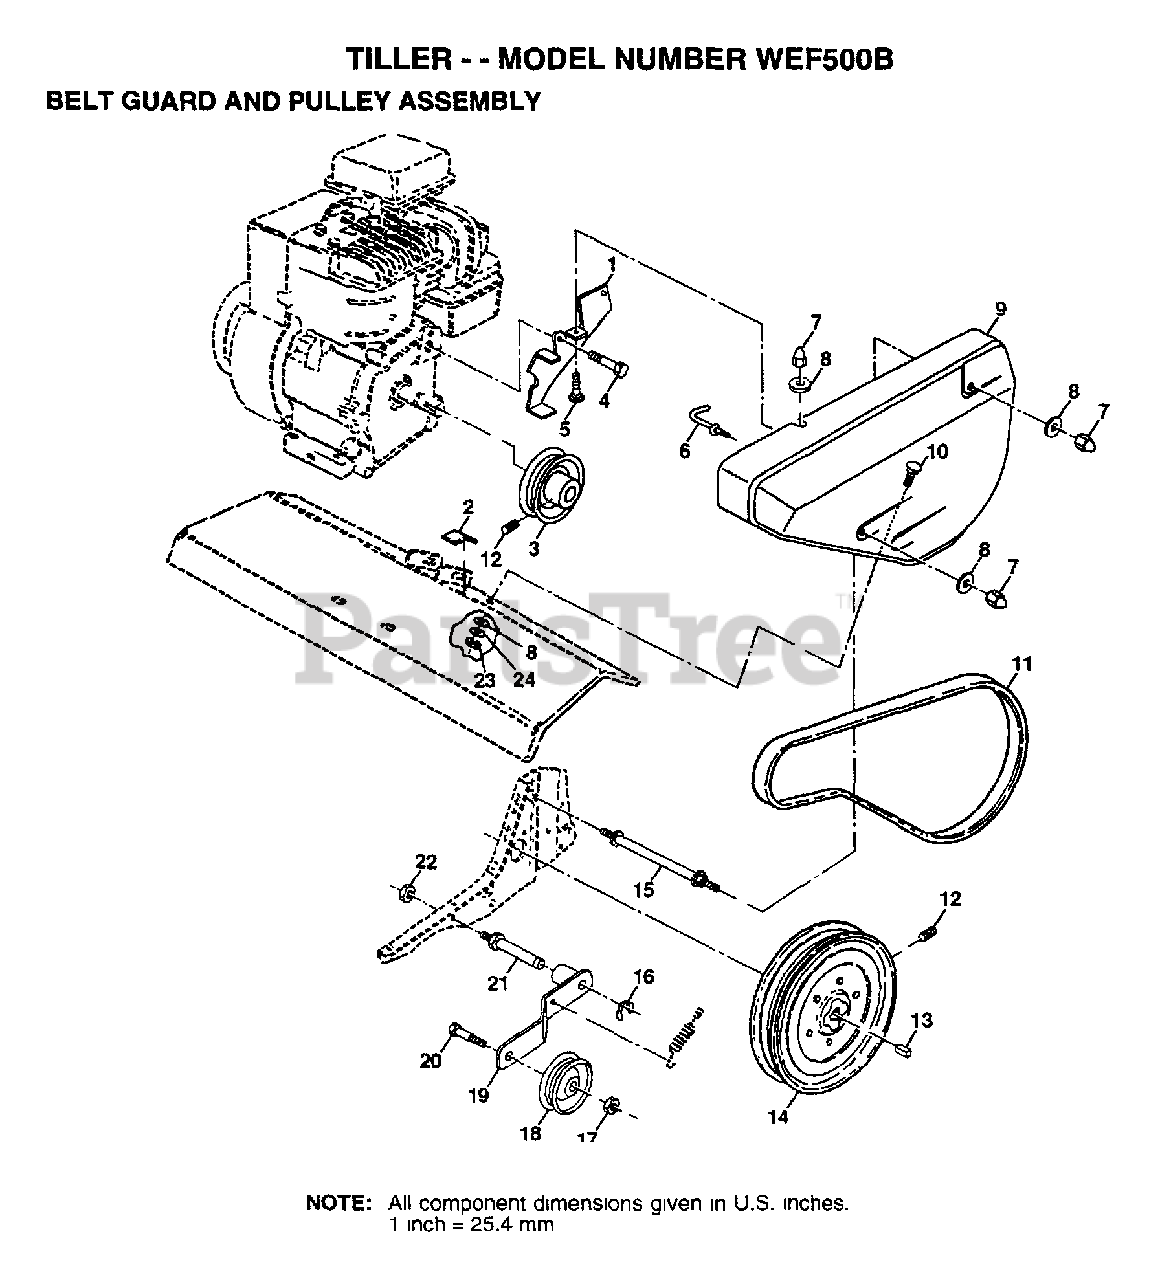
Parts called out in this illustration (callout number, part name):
2	PAD IDLER TI
3	ENGINE PULLEY
5	BOLT
7	NUT-CAP TI
8	WASHER
9	GUARD.PNT.BELT
10	BOLT T
11	V BELT STD
12	SET SCREW
13	KEY T
14	TRANS SHEAVE RT
15	BOLT TI
16	KLIP RING TI
17	NUT
19	IDLER ARM TI
21	SHAFT IDLER TI
22	JAM NUT TI
24	LOCKWASHER
